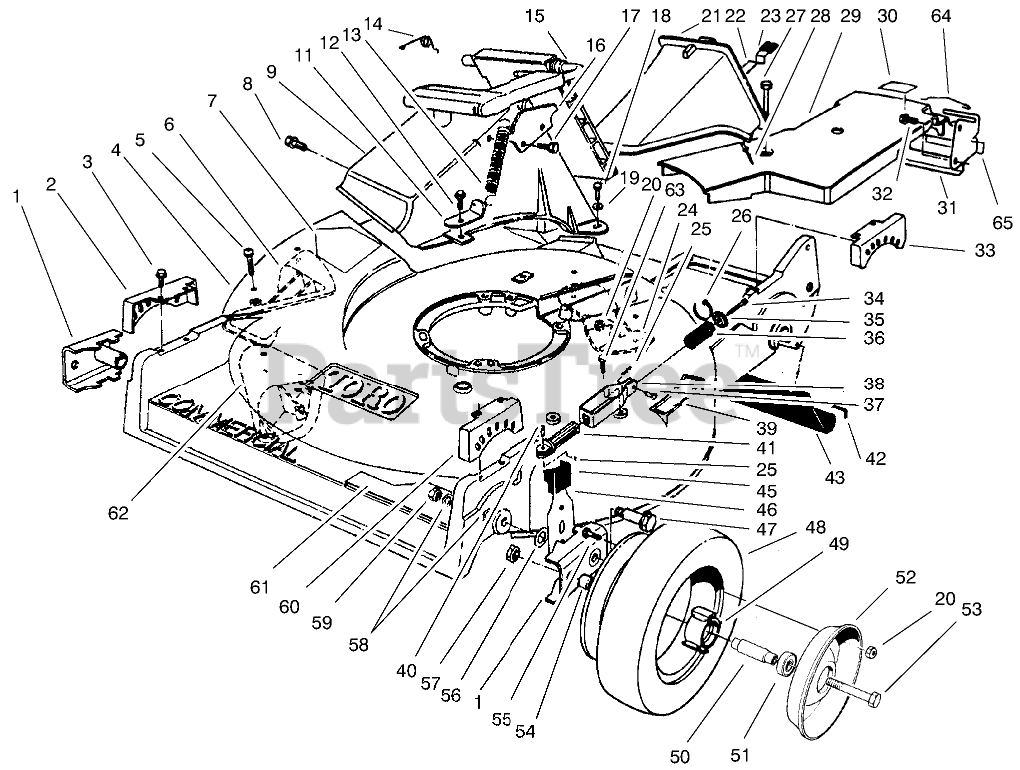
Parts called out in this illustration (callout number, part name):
1	ARM-PIVOT, FRONT
2	QUADRANT-FRONT, RH
3	SCREW-HWHTF
4	Housing-Commercial (Incl. Ref. #5-7, 24, & 62)(Incl. Ref. #28 pg. 4)
5	SCREW-PPH
6	KICKER-RH
7	DECAL-DANGER
8	SCREW AND WASHER ASM
9	DISCHARGE TUNNEL
9	TUNNEL-DISCHARGE
11	BRACKET-SPRING
12	SCREW-HWH
13	SPRING-DOOR
14	RETAINER-DOOR
15	DOOR ASSEMBLY
15	DISCHARGE DOOR ASM
16	DOOR LATCH PLATE
16	LATCH-PLATE
17	SCREW-PLASTITE
18	SCREW-HH
19	WASHER-FLAT
20	NUT-LOCK, NI
21	Plug-Discharge (Incl. Ref. #22, 23, & 28)
22	LATCH-PLUG, DISCHARGE
23	GRIP-LATCH
24	KICKER-REAR
25	PIN-COTTER
26	TIE-CABLE
27	SCREW-HHFTF
28	RIVET-HEAD, FLAT
29	BELT COVER
30	LABEL-GREASE
31	BRACKET-ADJUSTMENT, TRACTION
32	SCREW-HWHTF
33	QUADRANT-REAR, LH
34	SCREW-HWHTF
35	RETAINER-SPRING
36	SPRING
37	PIN-CABLE
38	Bracket-Spring
39	STEP PAD DECAL
40	PIN-SPRING
41	GUIDE-SPRING
42	ROD-SHIELD
43	SHIELD-TRAILING
45	KNOB-ARM
46	FRONT SPRING ARM ASM
47	BOLT-WHEEL
49	HUB-BEARING
50	SPACER-BEARING
51	BEARING-WHEEL
52	Wheel-Half
53	SCREW-HH
54	SPACER-WHEEL
55	SCREW-HH
56	WASHER-THRUST
57	NUT-LOCK, CONE
58	WASHER
59	NUT-LOCK
60	QUADRANT-FRONT, LH
61	DECAL - RECYCLER
62	KICKER-FRONT
63	SCREW-HH
64	RETAINER-CABLE
65	DECAL-POSITION, GEAR
